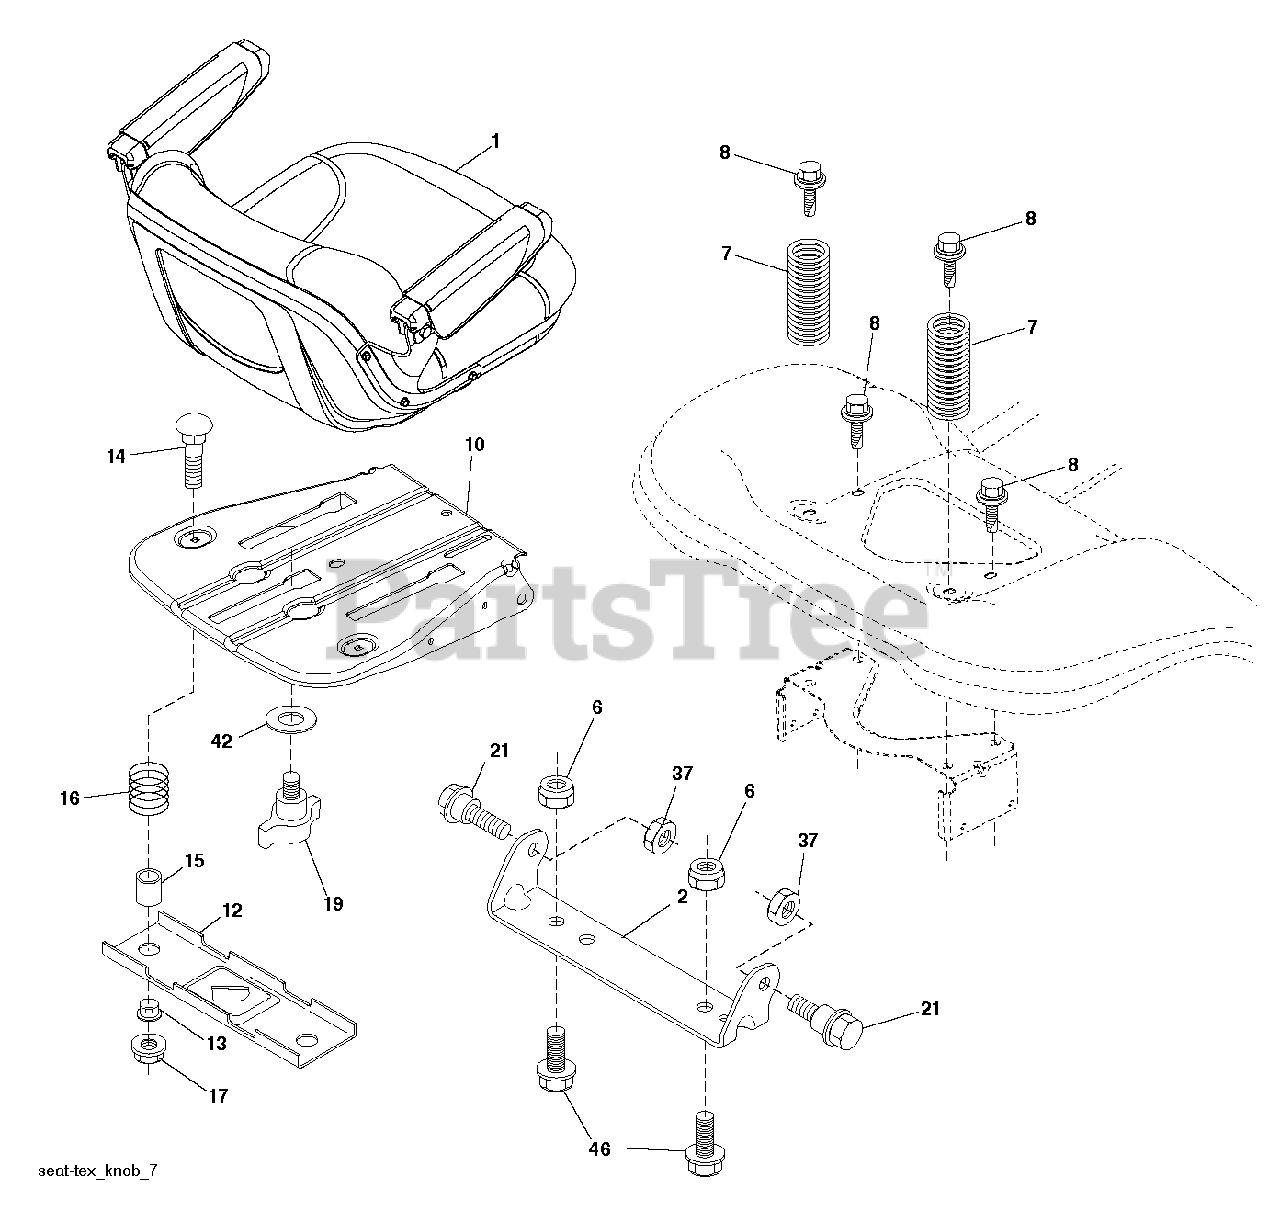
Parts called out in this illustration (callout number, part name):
1	SEAT.TP150.BLK.PPRO.KB/SL
2	BRKT.PIVOT.FENDER
6	NUT
7	Compression Spring, Seat Black
8	BOLT, 5/16-18 X 1 3/4
10	PAN.ASM.SEAT.SHORT.SLD.ADJ.TEX
12	BRKT.MNT.OPC.SW.SEAT.
14	BOLT.ROUND.HEAD.SQUARE.NECK
15	SPACER SPLIT 28X.96
16	SPRING COMPRESSED
17	NUT T
19	KNOB.SEAT.ADJ.
21	Shoulder Bolt, 5/16-18 X 5/8
37	NUT.71038.31-18.HEX.NYLOCK
42	WASHER.CUP.SEAT.
46	BOLT.3/8-16X1;1.25OD.WSHR.SEMS
